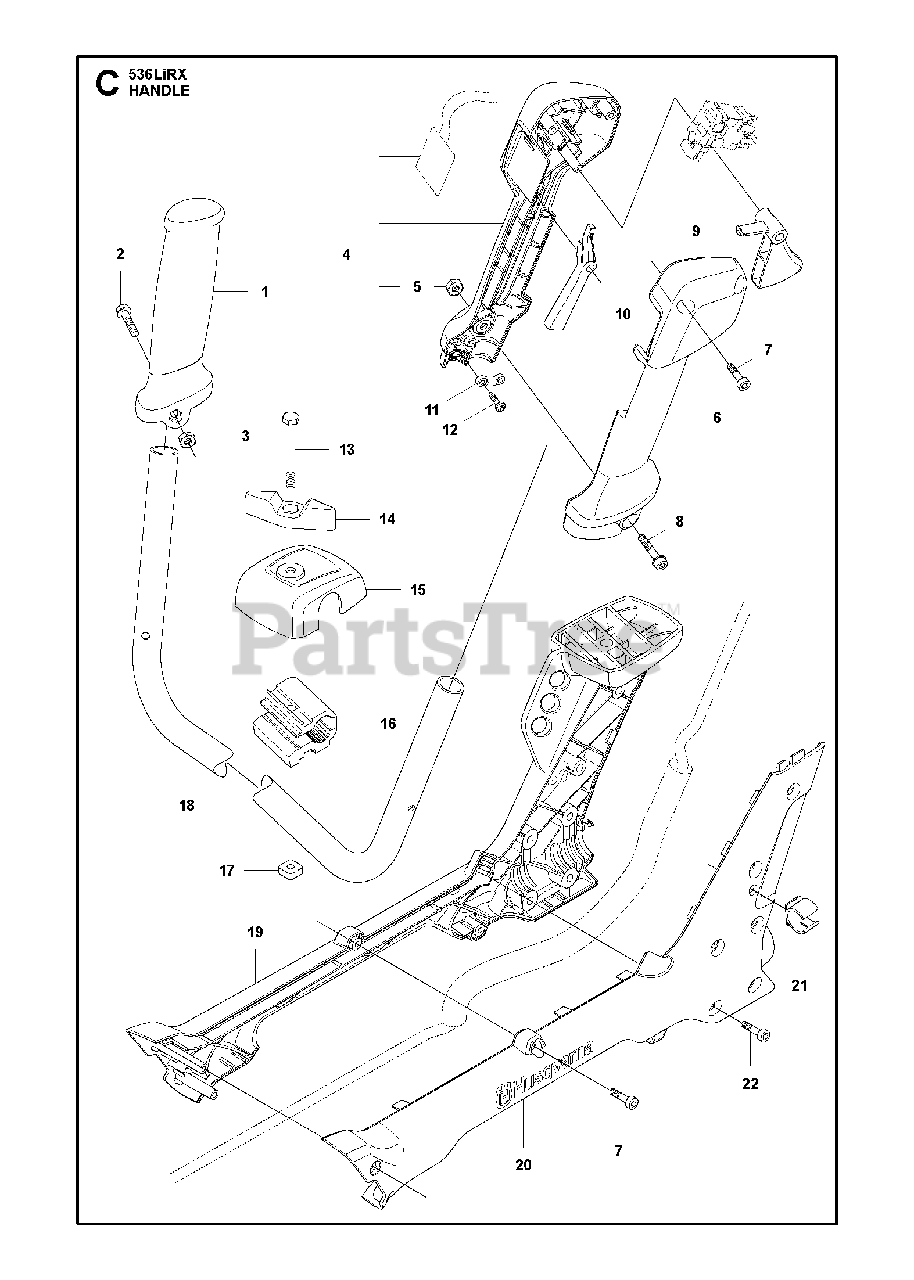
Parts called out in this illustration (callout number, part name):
7	SCREW
8	%SCREW
15	COVER HANDLE BAR
18	HANDLEBAR MACHINED
